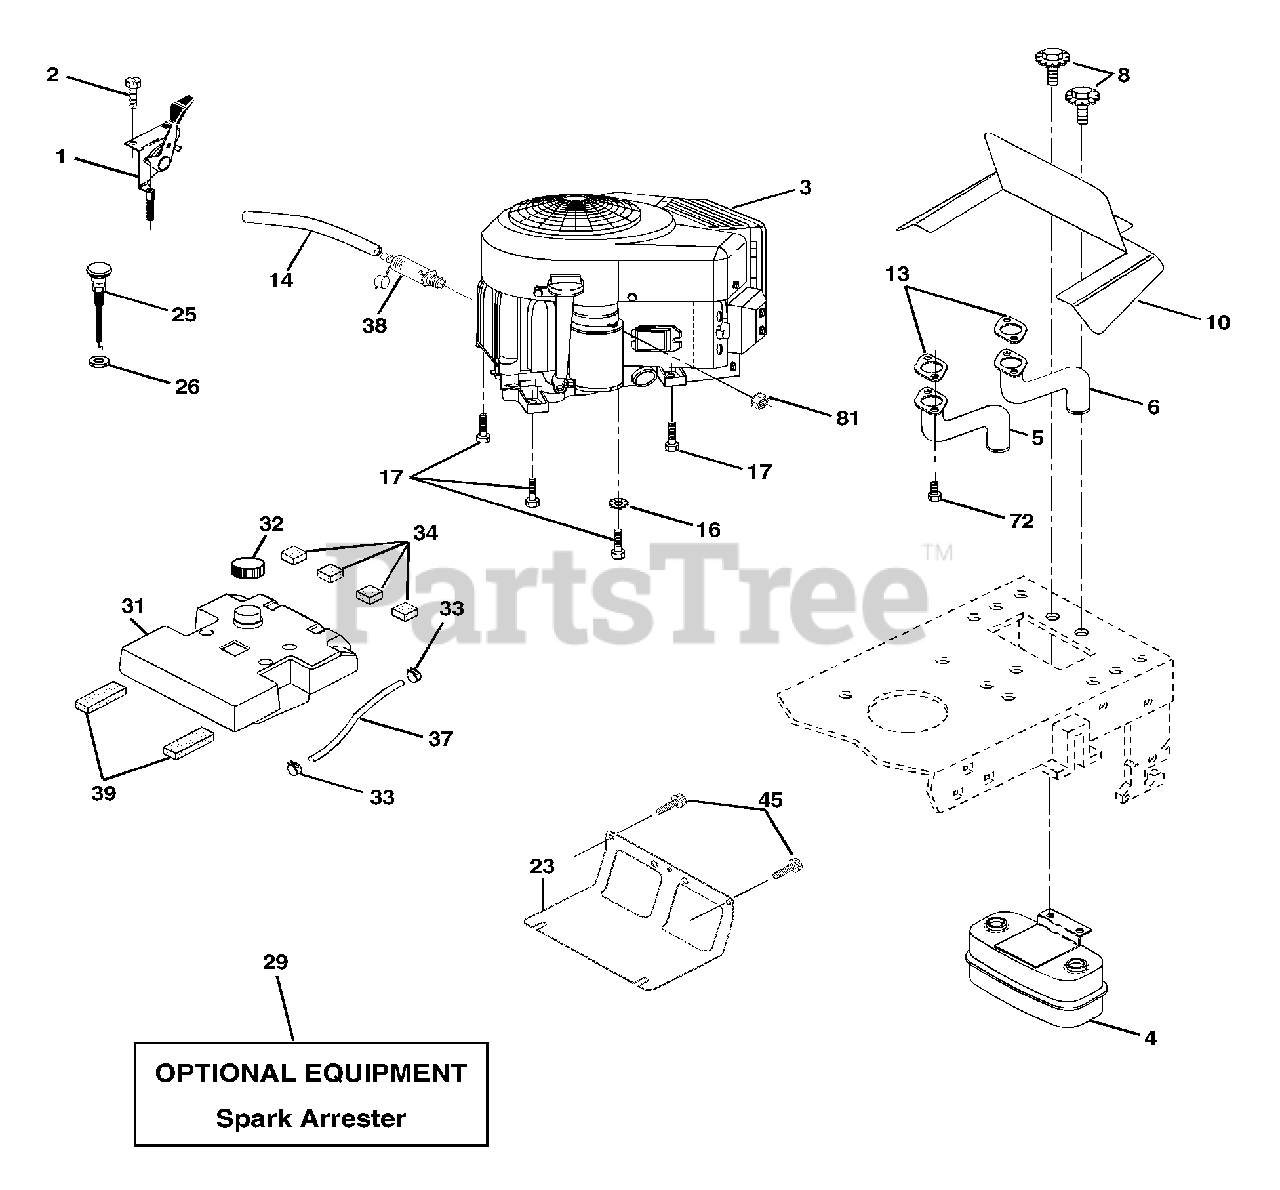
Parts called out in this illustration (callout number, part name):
1	Control Throttle
2	Screw Hw Hd Hi-Lo #13-16 x 3/4
4	Muffl er Asm Twin Lo-Tone
5	Pipe Exhaust LH Intek
6	Pipe Exhaust RH Intek
8	Bolt 5/16-18 Unc x 3/4 w/Sems
10	Shield Browning Intek II
13	Muffl er Gasket
14	Tube Drain Oil Easy
16	Washer Lock Ext Tooth 3/8
17	Screw Thdrol 3/8-16 x 1-1/2
23	Shield Heat
25	Choke Control
26	Nut, Keps 3/8-24 Unf
29	Kit Spark Arrestor (Flat Scrn)
31	Tank Fuel 3 50 Rear
32	Cap Asm Fuel W/sym Vented
33	Clamp Hose Black
34	Pad, Spacer
37	Line Fuel
38	Plug Drain Oil
39	Pad, Idler
45	Screw Hexwsh Thdr 3/8-16 x 3/4
62	Washer Lock 5/16
72	Screw Hex Hd Cap 5/16-18 x 3/4
81	Nut Keps Hex 1/4-20 Unc
